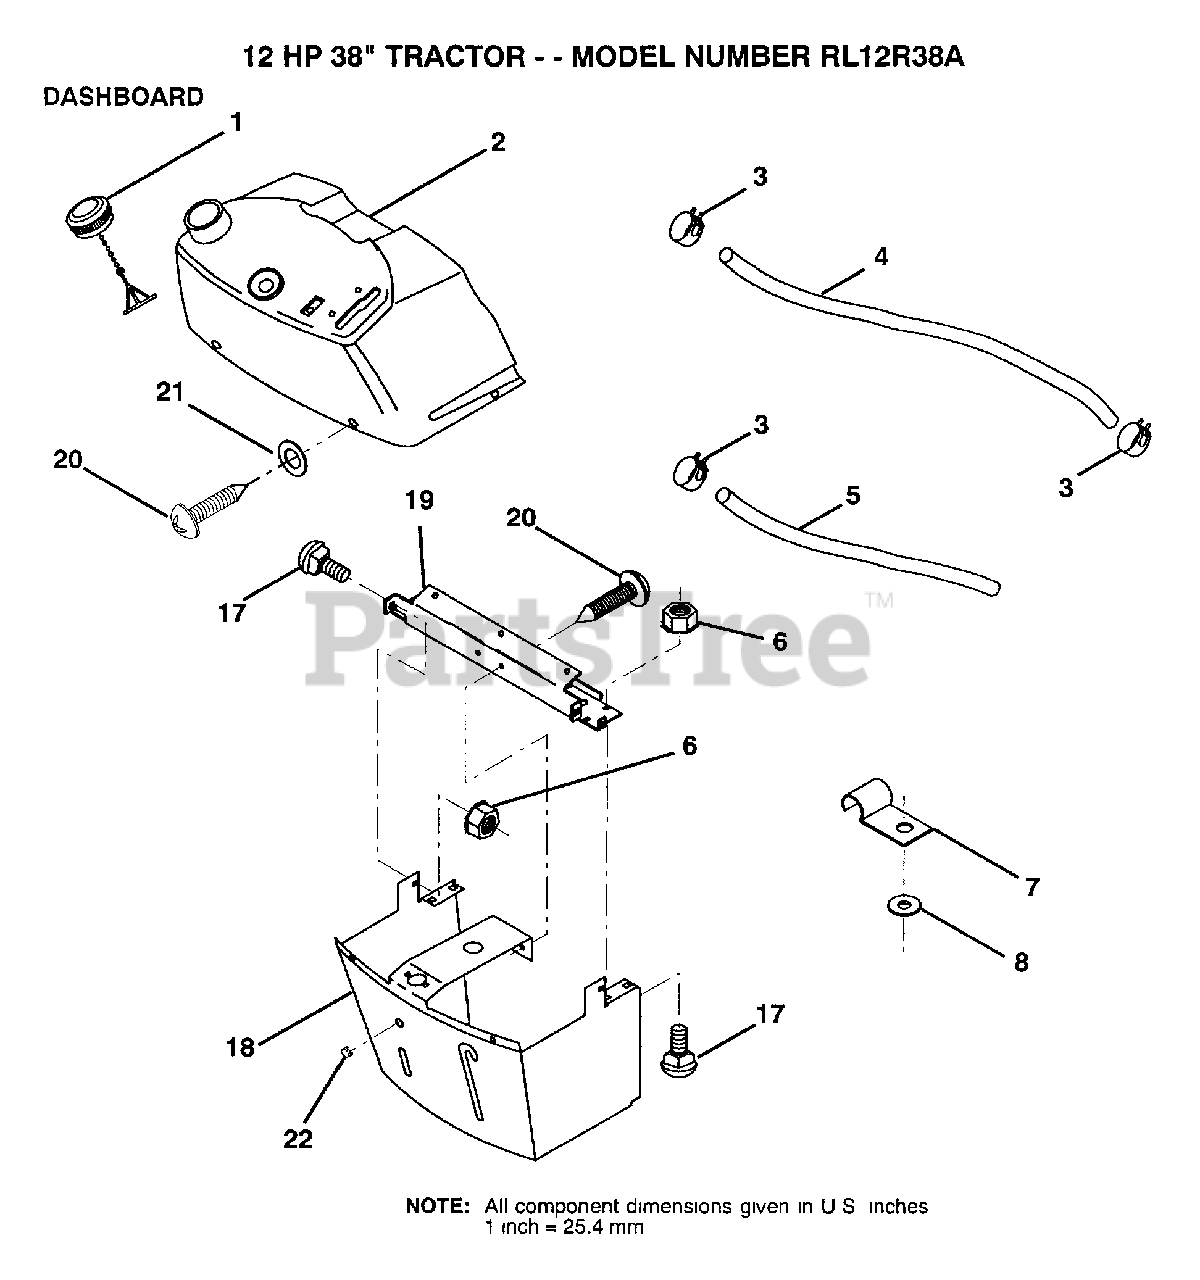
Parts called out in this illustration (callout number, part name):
3	HOSE CLAMP
5	FUEL LINE T
6	NUT
7	CLIP T
8	WASHER PM
17	BOLT
18	SUPT ASM DASH
19	CROSS BRACE
22	PLUG DOME
